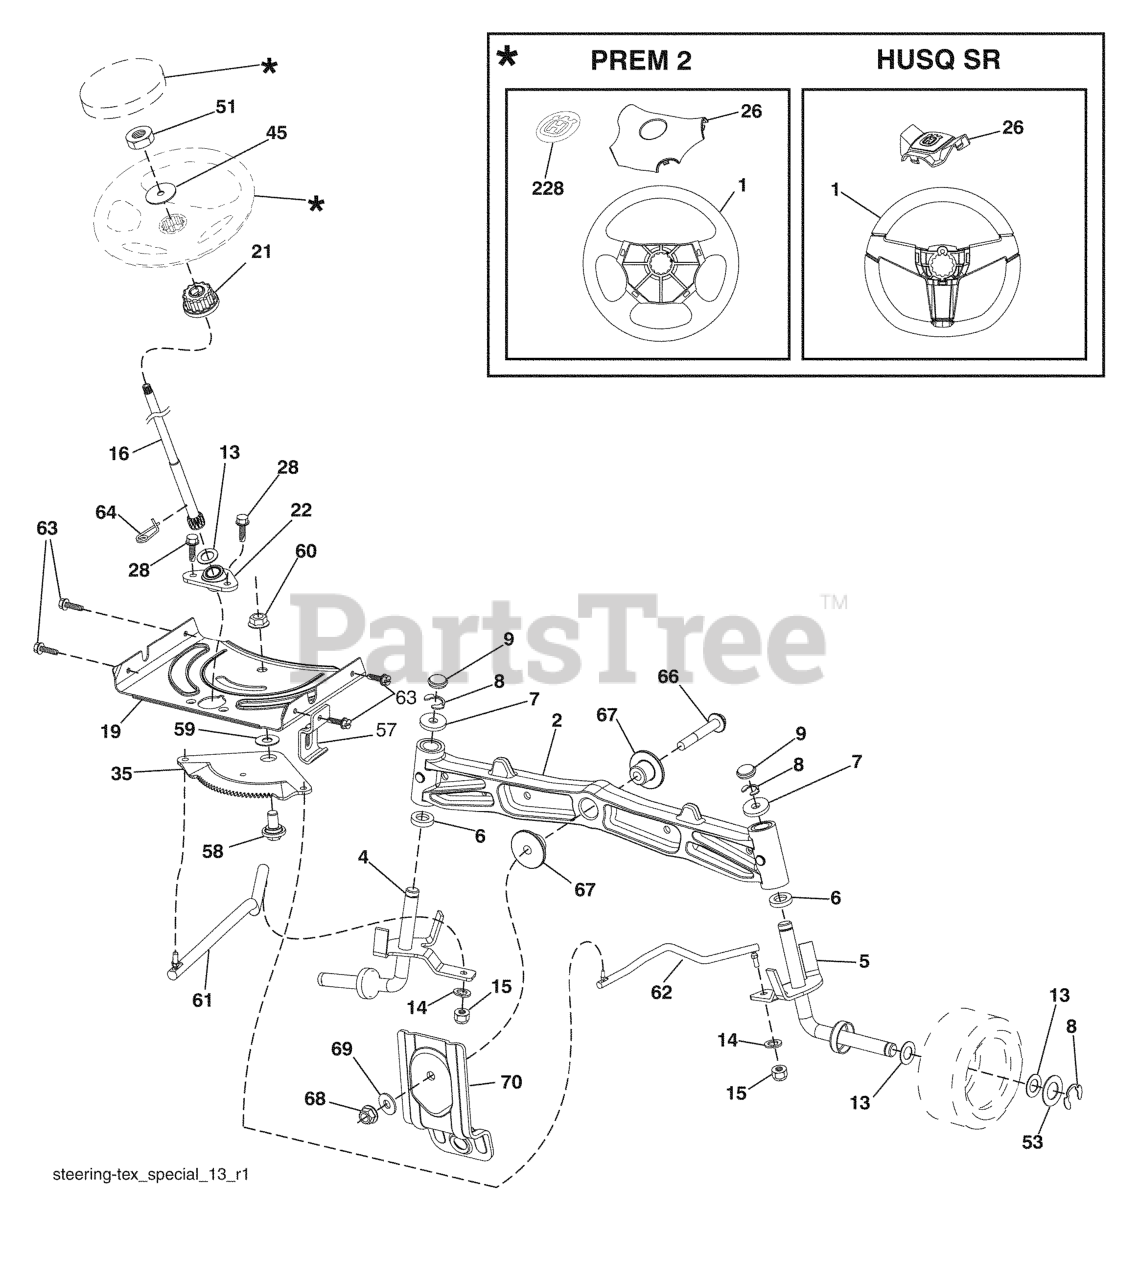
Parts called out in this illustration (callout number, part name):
1	RP WHEEL.STEER.HUSQ.PREM.OVMLD
2	AXLE.CAST.IRON
4	SPINDLE.WELDED.LH.16"TEX
5	SPINDLE.WELDED.RH.16"TEX
6	THRUST WASHER
9	CAP.SPINDLE.BLACK
14	WASHER, LOCK 3/8
15	NUT CROWNLOCK 3/8-24
16	SHAFT, STEERING
19	PLATE.STEER.DDL.NLT/NG
21	ADAPTER, WHEEL STNG..
22	BUSHING.ASM.STEERING.A
26	RP INSERT.CAP.WHL.STRG.HUSQ.
28	SCREW, 3/8-16X3/4
35	GEAR.SECTOR.PLATE.DDL.
45	WASHER 9/16"ID, 2 3/8"OD
51	NUT.HEX.1/2-20
53	WASHER.HARDENED
57	BRKT.UPSTOP.GT/LT.TEX
58	BOLT.SHOULDER.SECTOR.P
59	WASHER.THURST.SECTOR.S
60	NUT FLANGE LOCK 5/8-11
61	DRAGLINK.LH.BALLSTUD.D
62	DRAGLINK.RH.BALLSTUD.D
63	SCREW
64	RETAINER.CLIP.SPRING.S
66	BOLT HEX FGHD 7/16-14 X 3 SERR
67	BUSHING.PM.FRONT AXLE
68	NUT.LOCK.FLANGE.7/16
69	WASHER.1.5X.505X.118
70	BRKT.DECK.SUSPENSION.F
228	DECAL.WHEEL.STRG.LGN.H
